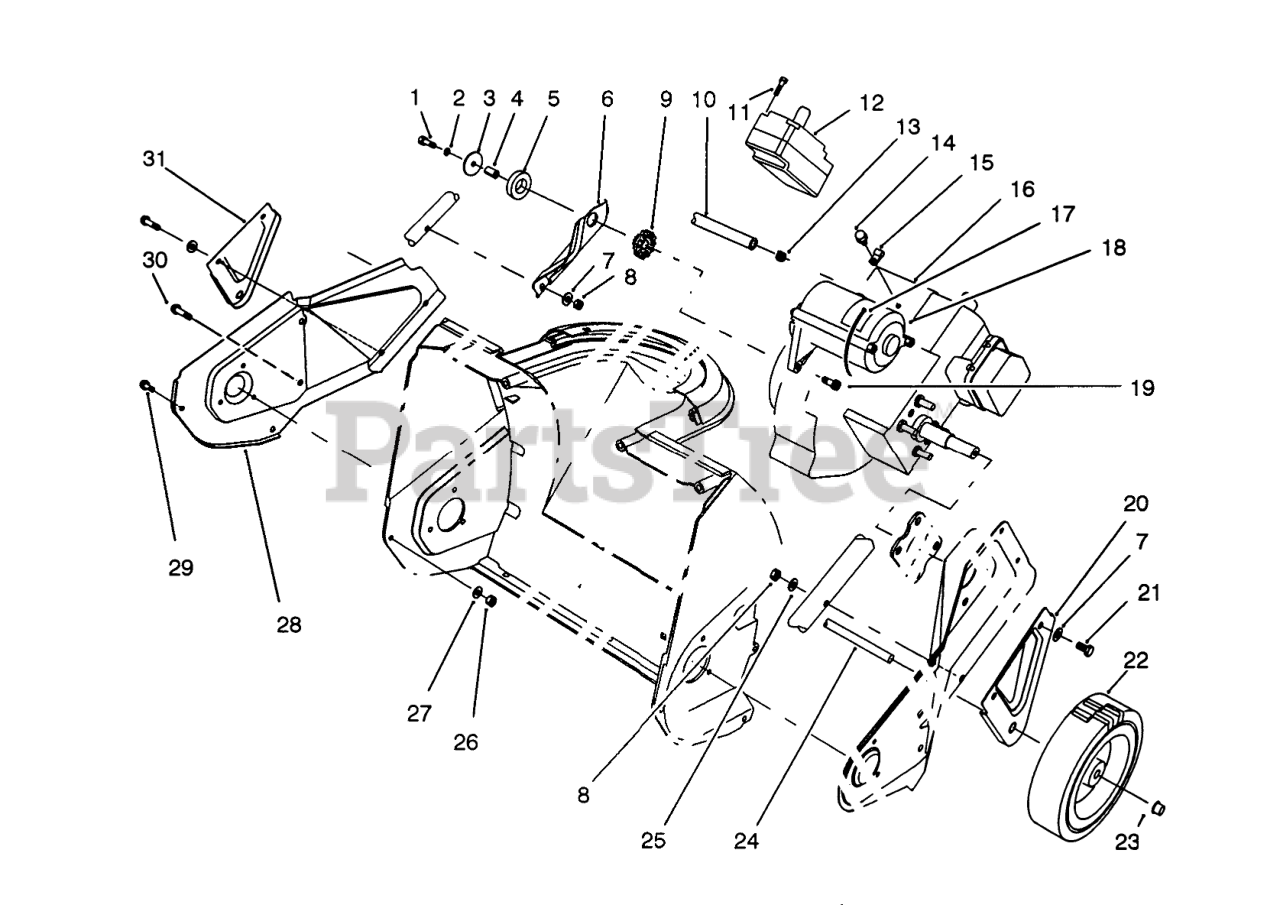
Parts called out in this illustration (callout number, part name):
1	SCREW-HH
2	WASHER-LOCK
3	WASHER-FLAT
4	SPACER-TUBULAR
5	Ring-Isolator
6	Support-Engine
7	WASHER-FLAT
8	NUT-LOCK, NI
9	BUSHING-ISOLATOR
10	LINE-GAS
11	SCREW-PLASTITE
12	ASM-Switch Housing
13	Clamp
14	SCREW-HWH
15	CLAMP
17	TIE-CABLE
18	Starter Motor Assembly
19	SCREW-HH, TORX
20	Bracket-Wheel
21	SCREW-HH
22	WHEEL
23	RETAINER-PUSH ON
25	WASHER
26	NUT-LOCK, NI
27	WASHER-FLAT
28	Sideplate-RH
30	SCREW-PLASTIC
31	Bracket-Wheel
